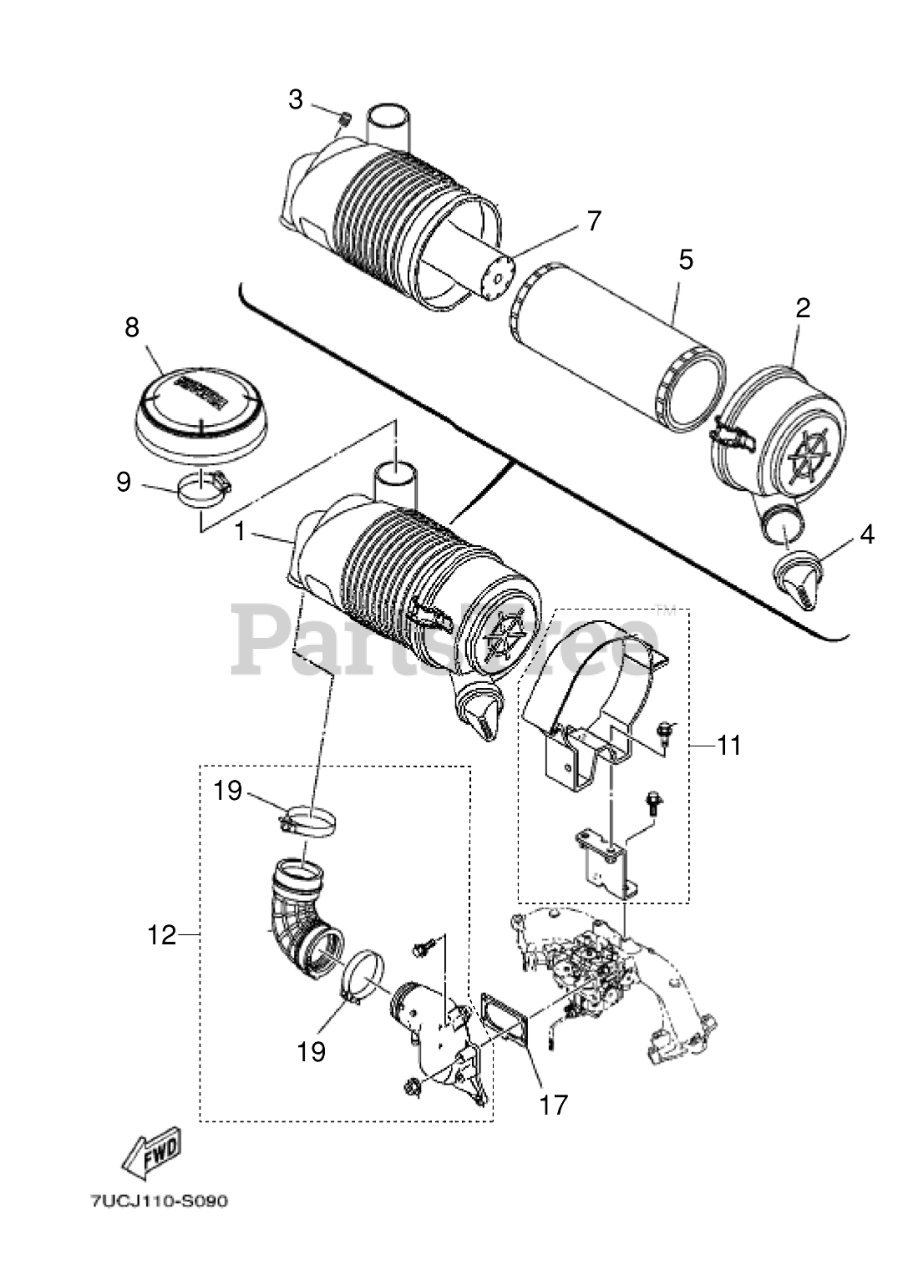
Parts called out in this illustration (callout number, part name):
1	AIR CLEANER ASSY YAMAHA PN: 7U
2	CAP CLEANER CASE 1 YAMAHA PN:
3	PLUG YAMAHA PN: 7UD-E432A-00
4	PLUG BLIND YAMAHA PN: 7UD-E443
5	AIR FILTER OUTER ELEMENT YAMAH
7	AIR FILTER INNER ELEMENT YAMAH
8	COVER AIR RAIN CAP YAMAHA PN:
9	HOSE CLAMP ASSY YAMAHA PN: 904
11	PLATE KIT INTAKE STAY KIT
12	JOINT INTAKE JOINT KIT
17	GASKET MANIFOLD 2 YAMAHA PN: 7
19	HOSE CLAMP ASSY YAMAHA PN: 904
